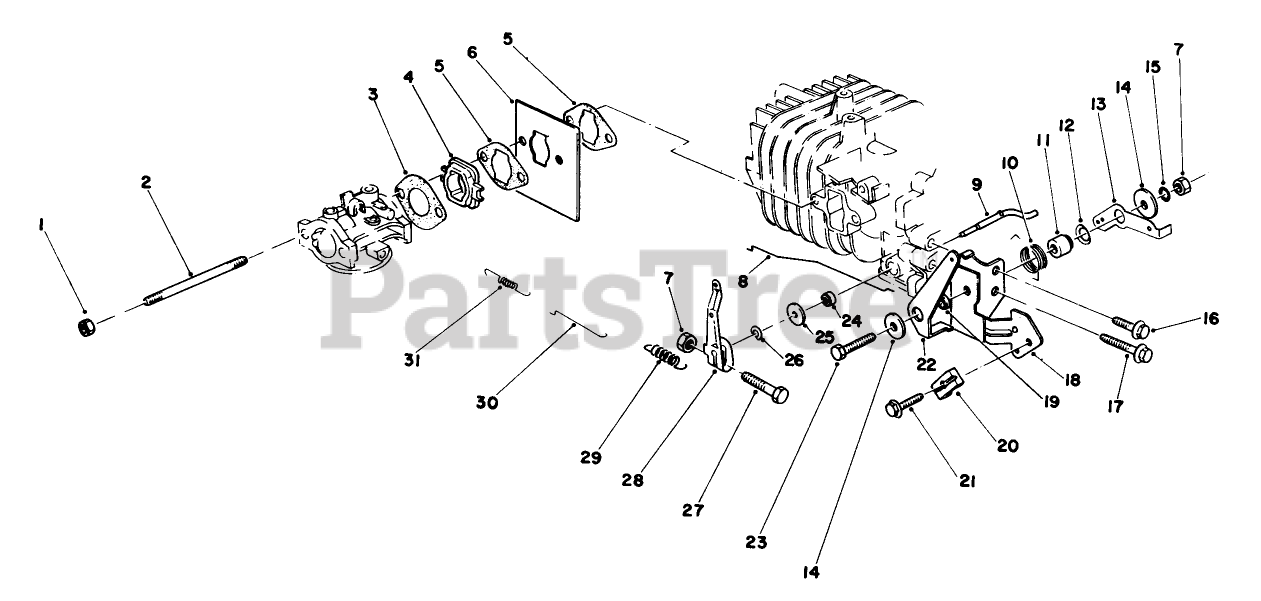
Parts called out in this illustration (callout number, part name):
2	CARB STUD BOLT
3	GASKET-CARB
4	INSULATOR
5	GASKET-CARBURETOR
15	LOCKWASHER
20	CLAMP-CABLE
24	SEAL-OIL
25	WASHER
30	ROD-CARBURETOR
31	SPRING
